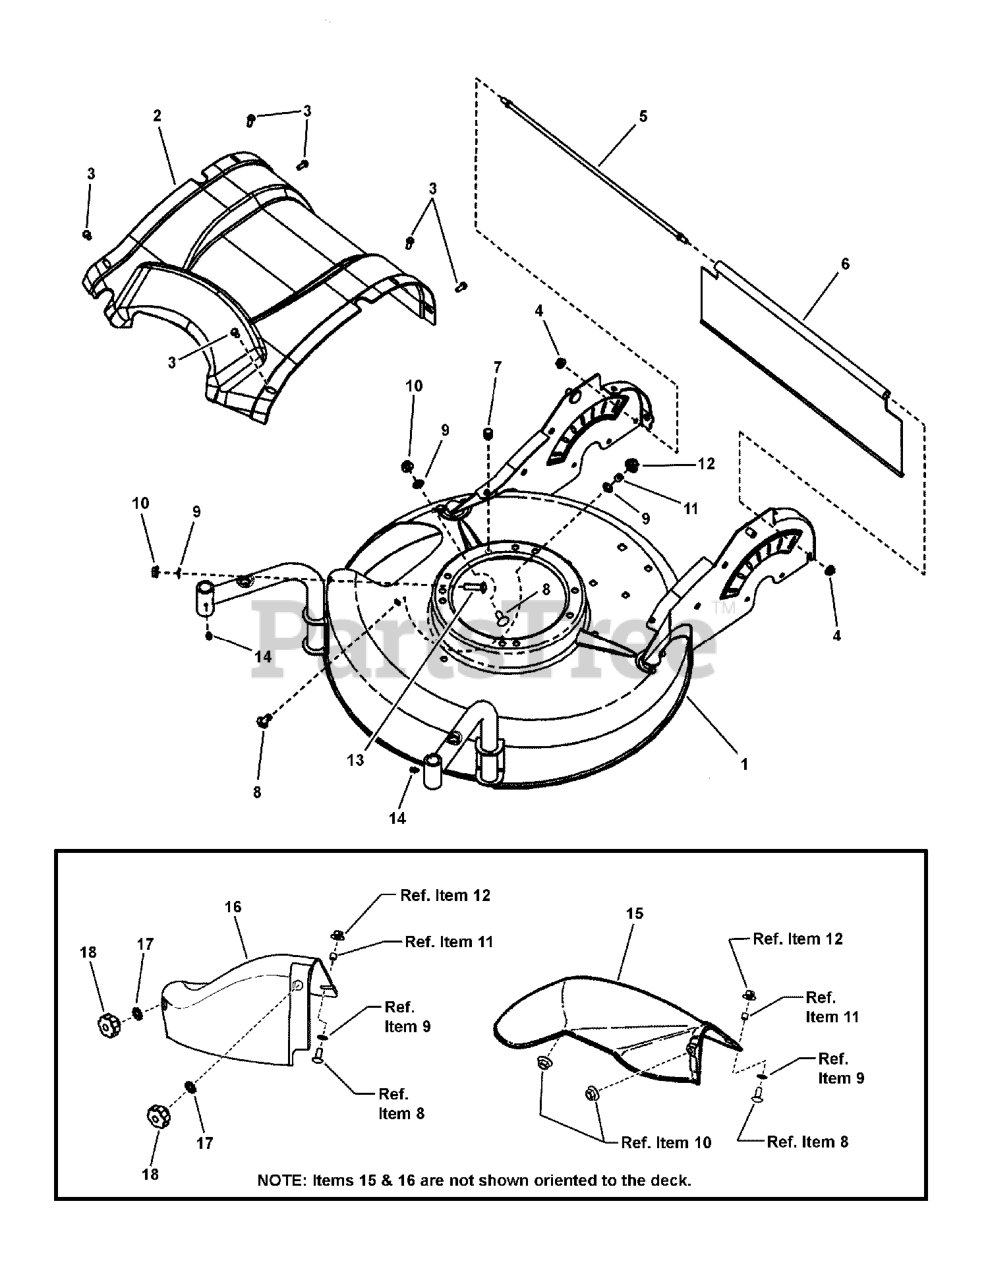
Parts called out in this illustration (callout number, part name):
1	WELDMENT, Deck, 21" Swivel Wheel, Value Line
2	COVER, Rear, Belt/Transmission
3	SCREW, 7MM x 1 x .550, AB Point
4	NUT, 1/4-20 Hex Flange Lock, YZ
5	ROD, Trail Shield (1/4-20 thread, both ends)
6	SHIELD, Trail
7	PLUG, Hole, .44" OD
8	BOLT, 5/16-18 x 3/4" Round Head Short Square Neck Carriage, GR 5
9	BOLT RETAINER, 5/16- Black
10	NUT, 5/16-18 Hex Flange Lock, GR 5
11	SPACER, .316 x .375 x .300/.310
12	NUT, 5/16-18- Large Flange Hex Center Lock, Black
13	BOLT, 5/16-18 x 1-1/8" Round Head Short Square Neck Carriage, GR 5
14	LUBE FITTING, 3/16" Press-Fit
15	CHUTE, 21 Side (Ext)
16	COVER, 21 Deck
17	WASHER, 5/16 Internal/External Lock
18	KNOB, Fluted (5/16-18 Thread x .633)
